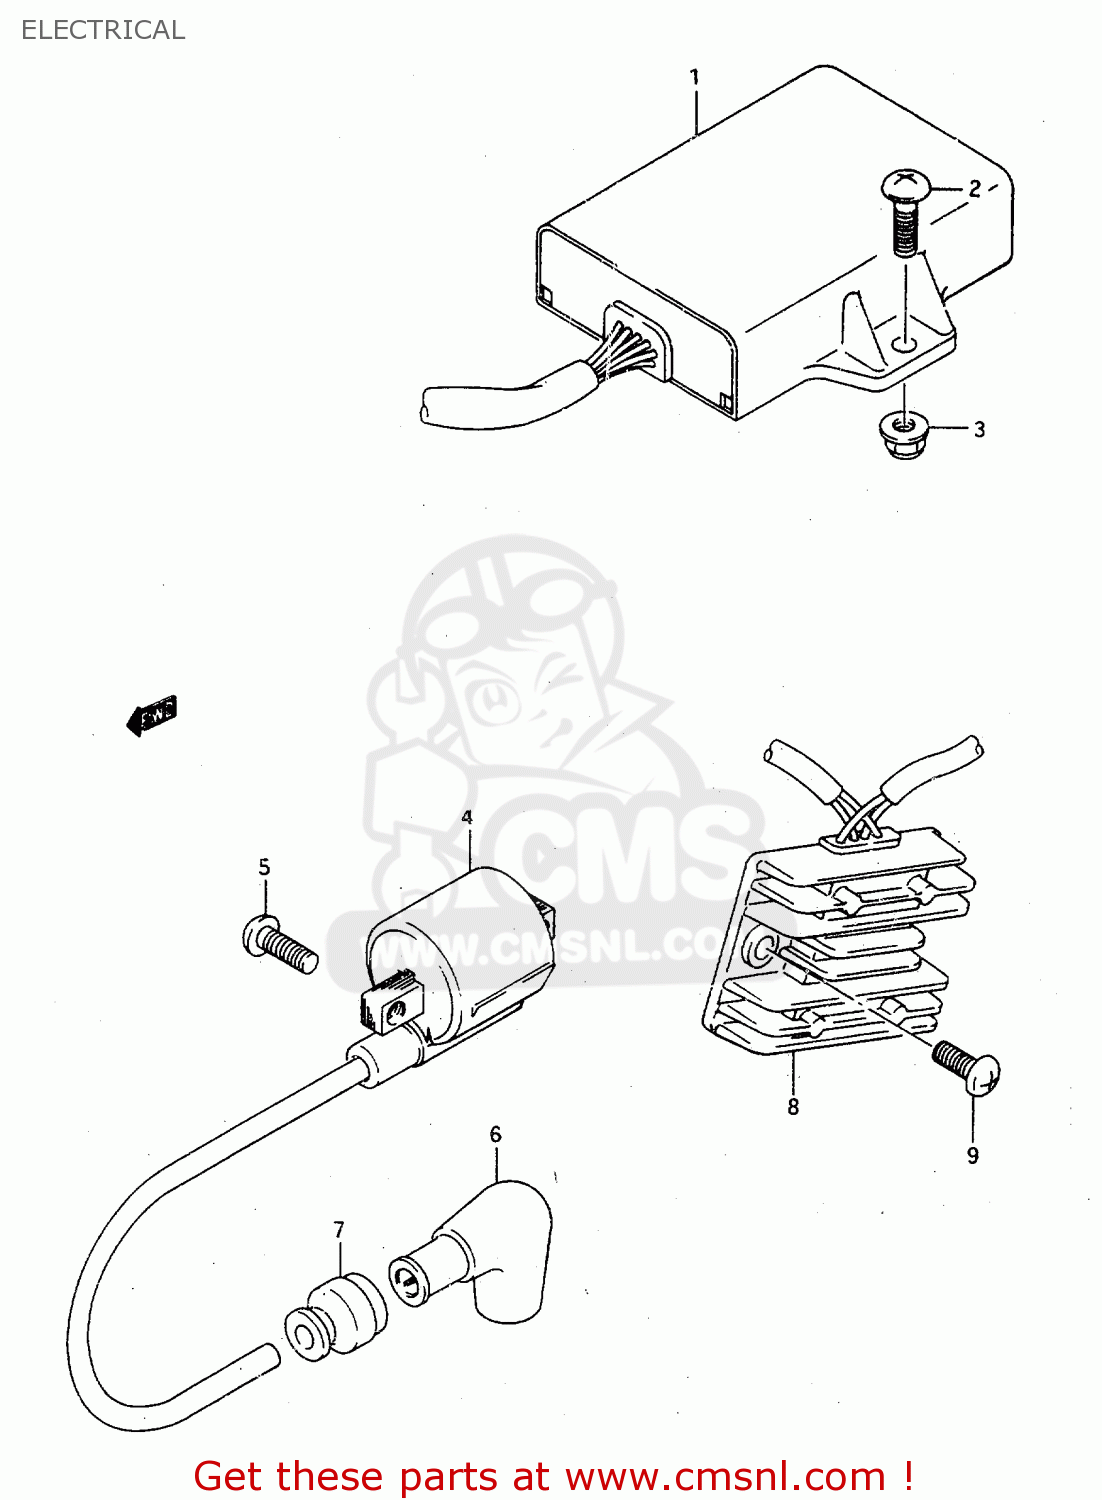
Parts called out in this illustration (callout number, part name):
1	CDI UNIT
2	SCREW
3	NUT
4	COIL ASSY,IGNITION
5	SCREW
6	CAP,SPARK PLUG
7	SEAL,HIGH TENSION CORD
8	RECTIFIER ASSY
9	SCREW
